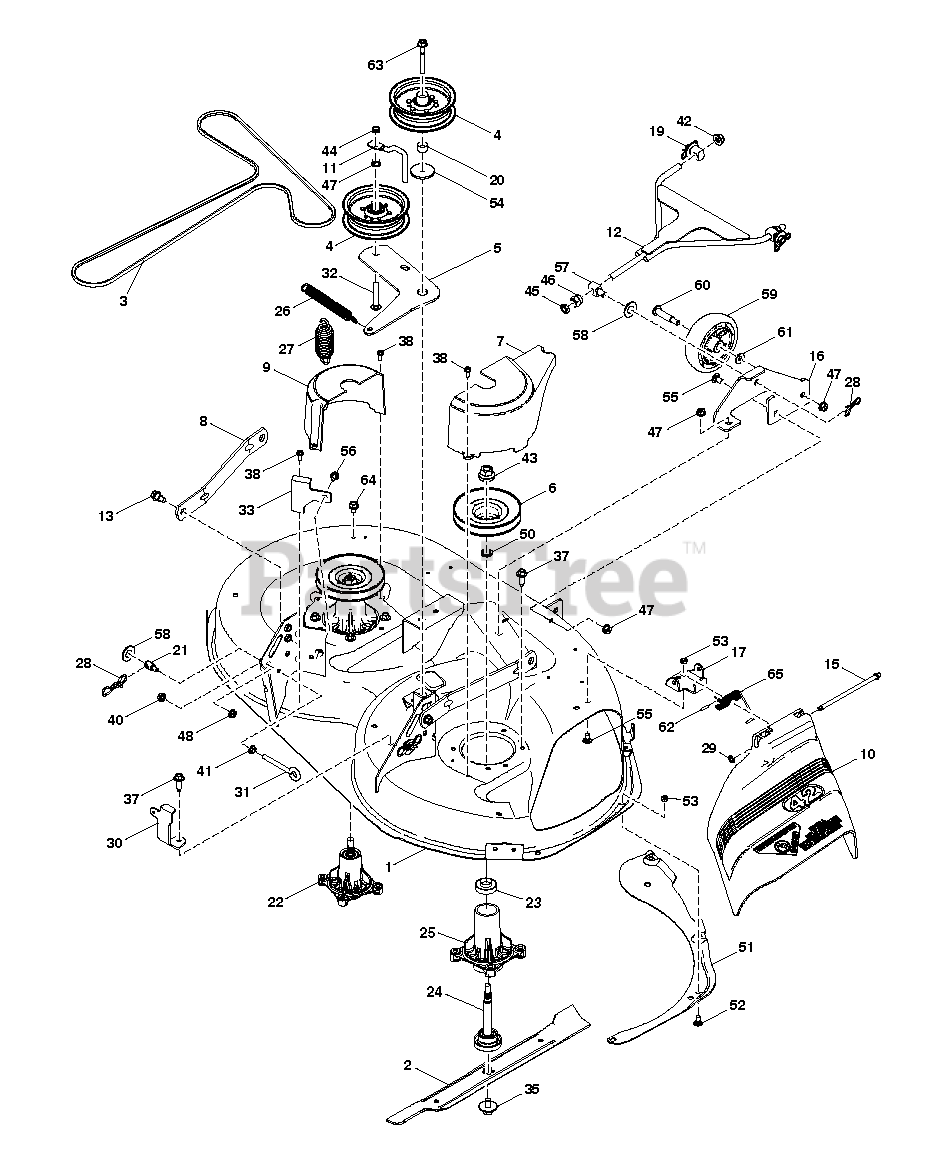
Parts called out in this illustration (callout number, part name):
1	KIT.42"DECK.W/DECALS.X668
2	42" HI-LIFT BLADE
3	BELT 42 STAMPED RZ DECK DRIVE
4	PULLEY.IDLER.2006
5	ARM 42 STAMPED RZ CLUTCHING AR
6	PULLEY.MANDREL.46"
7	COVER 42 STAMPED RZ RH MANDREL
8	ARM.RFIXED.MOWER.SUSPNSIONX431
9	COVER 42 STAMPED RZ LH MANDREL
10	SHIELD.DEFLECTOR.MOWER.42"BLAC
11	KEEPER.BELT.IDLER.54"T
12	LINK.RZ.FRONT.WELDMENT.E-DIP
13	BOLT.SHOULDER
15	ROD.HINGE
16	BRACKET.FRONT.SUSPENSION.X668
17	BRKT.DEFLECTOR.38"2005+
19	BUSHING SPHERICAL SUSP. FRONT
21	STUD.FASTNER.W/ANTI-ROTATE
22	MANDREL.W/SPCR.BRG.SHRT.NONRVL
23	BEARING.MANDREL.TOP.EXTENDED
24	SHAFT
25	HOUSING, MANDREL 48"
26	SPRING.MOWER.DRIVE.ELECTRIC
28	PIN.COTTER.5/16.BOW TI
29	NUT PUSH M
30	BRACKET 42 STAMPED RZ RH REAR
30	BRCKT.REAR.DECK.UPSTOP.RH.X668
31	EYE BOLT 5/16 X 3.50
32	CARRIAGE BOLT 3/8-16 X
33	BRACKET 42 STAMPED RZ LH REAR
33	BRCKT.REAR.DECK.UPSTOP.LH.X668
35	SCREW.SEMS.7/16-20X1.HEX.HEAD
37	BOLT.HEX.WASHR.HED.313-18X1.19
38	SCREW.1/4-20X5/8
40	NUT 5/16C WHIZ
41	5/16-18 NYLOC FLANGE NUT
42	7/16-14 HEX NUT W/NYL RING ZD
43	NUT.FLANGE.LOCK.TOP
45	NUT **
46	NUT, LIFT LINK 7/16-20
47	NUT LOCK FLG 3/8-16 UNC
48	NUT LOCK HEX FLANGE 5/16-18
50	WASHER.SPACER.MANDREL
51	BAFFLE DECK 42 SD BLACK
52	BOLT
53	LOCKNUT
54	SPACER.RETAINER.MOWER
56	SCREW, 3/8-16X3/4
57	SWIVEL.TRUNION.LINK.DECK.FRONT
58	WASHER
59	WHEEL.GAUGE.RALLY.NARROW
60	BOLT M
61	WASHER 5/16 FLAT
61	WASHER.5/16.FLAT.STE.STD.
62	CAP-SLEEVE LT
63	SCREW.HXWSH.3/8
64	SCREW 3/8-16X1/2
65	SPRING.TORSION.DEFLECT
